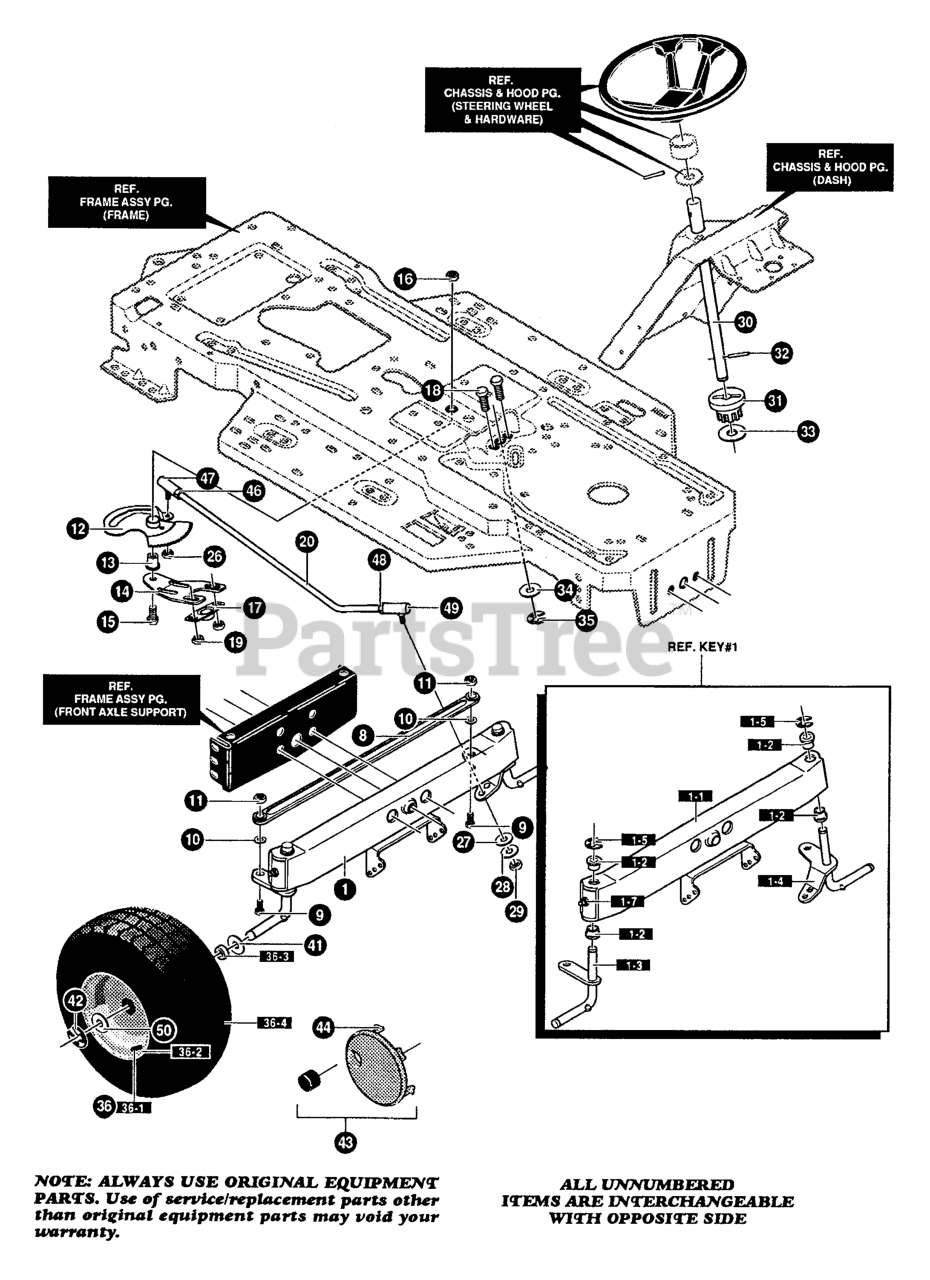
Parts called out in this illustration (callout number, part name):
1	ASSEMBLY, AXLE FRONT
1-1	ASSEMBLY, FRONT AXLE SUSPENDED
1-2	SPINDLE BEARING
1-3	ASSEMBLY, SPINDLE, RH
1-4	ASSEMBLY, SPINDLE, LH
1-5	RING, RETEX
1-7	ZERK, GREASE FITTING
8	TIE ROD ASSEMBL
9	SCREW, 3/8-16 X 1.75
10	WASHER, .393 x .68 x .10
11	NUT, 3/8-16
12	ASSEMBLY, SECTOR GEAR
13	BEARING, SLEEVE
14	SUPPORT, SECTOR GEAR
15	SCREW, 1/2-20 x 3.00
16	NUT, 1/2-20
17	BEARING, SEAL
18	SCREW, 5/16-24 x 0.75
19	NUT, 5/16-24
20	DRAG LINK
26	NUT, 3/8-24
27	WASHER, FLAT .531 X 1.06 X .095
28	WASHER, .459 X .78 X. 12
29	NUT, 7/16-20
30	SHAFT, STEERING
31	PINION, STEERING
32	PIN, DOWEL STEER
33	WASHER, FLAT .51 x 1.38 x .043
34	WASHER, FLAT .506 x .75 x .024
35	RING, RET E
36	TIRE & RIM ASSEMBLY, PU 15 X 6.0 X 6
36-1	VALVE STEM
36-2	RIM, WHEEL
36-3	BEARING
36-4	TIRE, 15 X 6-6
41	WASHER, FLAT .755 x 1.31 x .075
42	RING, RETEX
43	HUB CAP, 6"
44	CLIP, HUBCAP TINN
46	NUT, 3/8-24
47	BALL JOINT, 3/8
48	NUT, 7/16-20
49	BALL JOINT, 7/16-20
50	WASHER, FLAT .755 x 1.53 x .07
